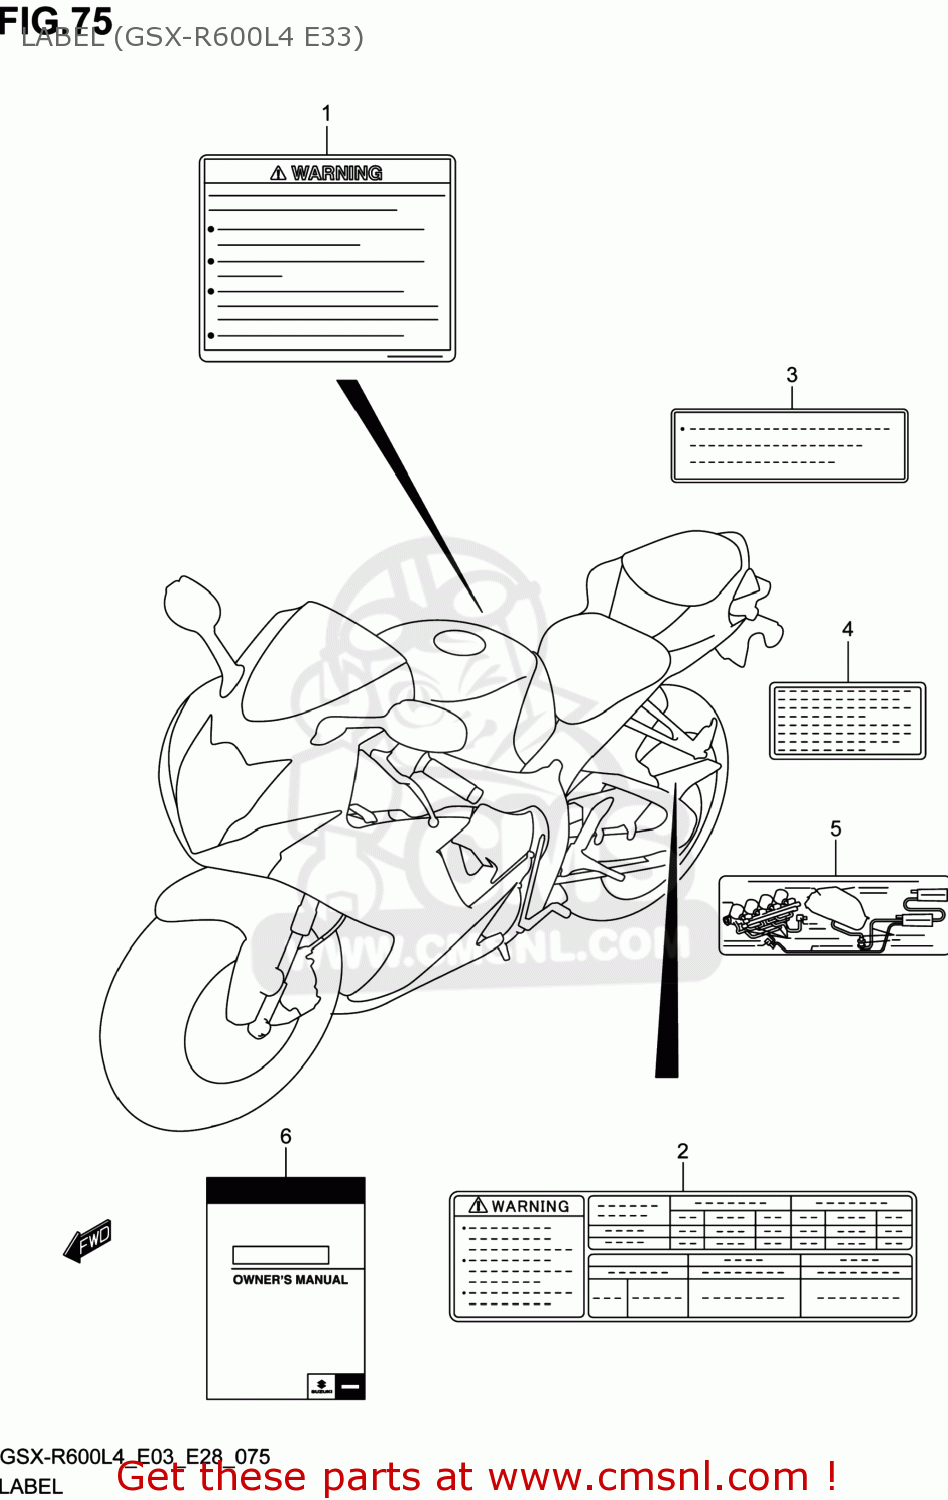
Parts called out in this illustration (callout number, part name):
1	LABEL,GENERAL WARNING
2	LABEL,TIRE INFORMATION
3	LABEL,FUEL INFORMATION
4	LABEL,MANUAL NOTICE
5	LABEL,VACUUM HOSE ROUTING
6	MANUAL,OWNER'S
